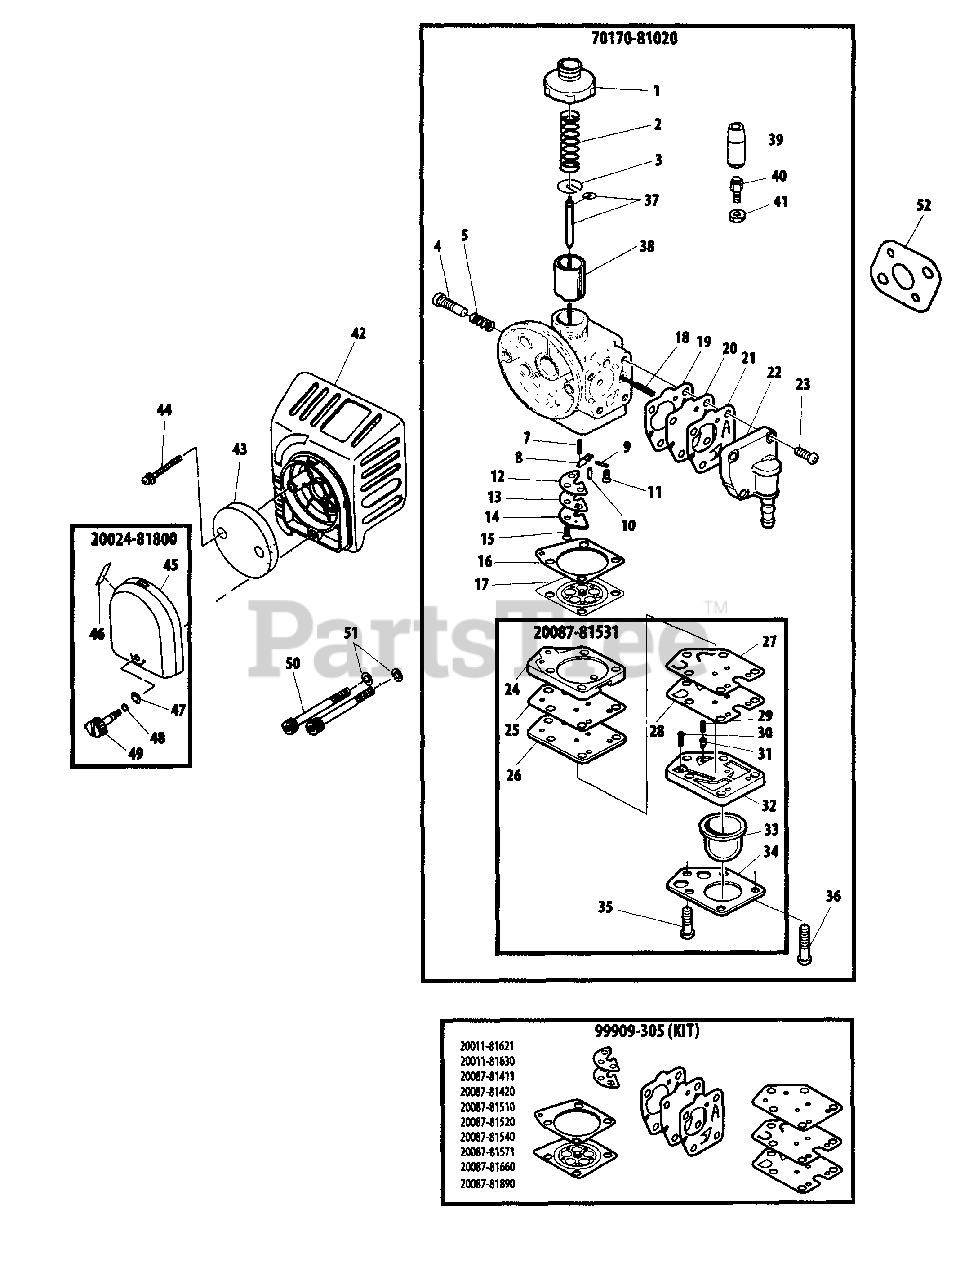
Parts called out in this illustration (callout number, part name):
1	CAP, CARBURETOR
2	SPRING
3	RETAINER
4	SCREW, IDLE ADJUST
5	SPRING
8	LEVER, METERING
9	PIN, METERING LEVER
10	VALVE, INLET NEEDLE
11	SCREW, METERING LEVER PIN
12	GASKET
13	VALVE, CHECK
14	PLATE
15	SCREW, METERING LEVER PIN
16	GASKET, METERING
17	DIAPHRAGM, METERING
18	SPRING
19	GASKET, METERING
20	DIAPHRAGM, METERING
21	VALVE, PUMP
22	BODY, PUMP
23	SCREW
24	BASE, PURGE
25	GASKET
26	PLATE, PUMP
27	DIAPHRAGM
28	GASKET
29	SPRING, RETURN
30	SPRING
31	VALVE
32	COVER, PUMP
33	BULB, PURGE
34	PLATE
35	SCREW
36	SCREW
37	NEEDLE, JET
38	SLIDE VALVE
39	GROMMET
40	NUT, CABLE ADJUST
41	LOCKNUT
42	CASE, AIR FILTER
43	FILTER, AIR
44	SCREW - 4X25
45	COVER, AIR FILTER
46	LABEL - CHOKE
47	WASHER - CONICAL
48	O-RING
49	THUMBSCREW
50	SCREW - 5X65
51	LOCKWASHER - 5
52	GASKET, INTAKE
